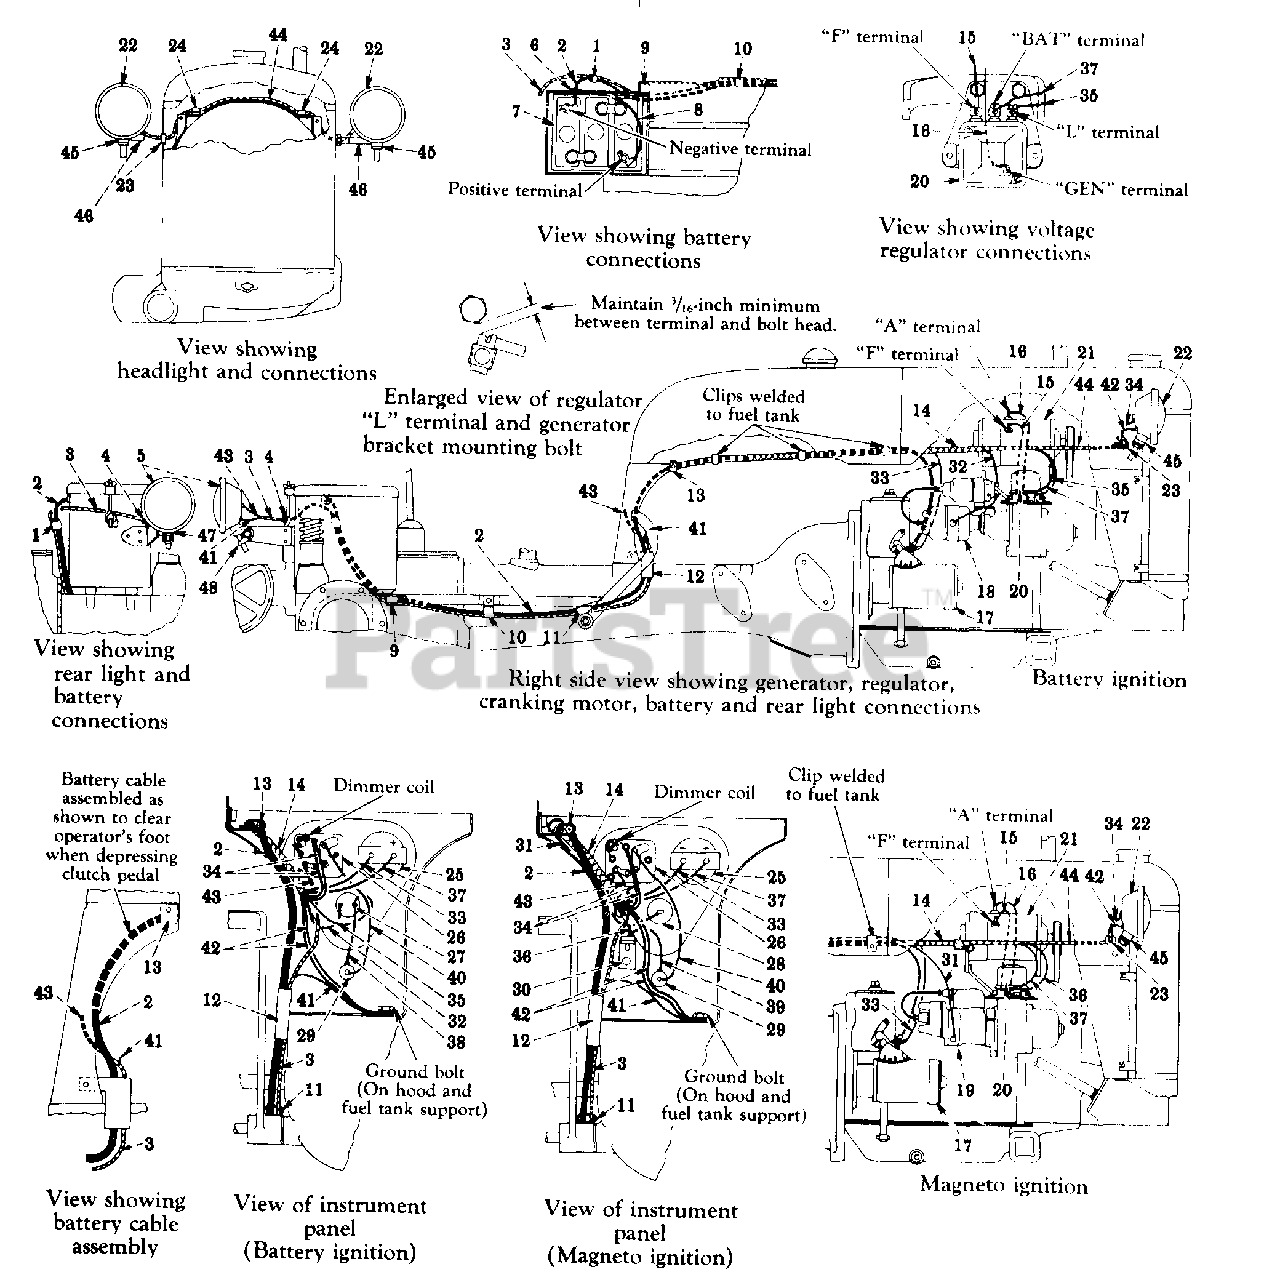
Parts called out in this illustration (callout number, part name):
1	STRAP, WRAPPING CABLE
2	CABLE BATTERY TO CRANKING MOTOR
3	CABLE, LIGHTING SWITCH TO REAR LIGHT
3	HARNESS ASSY, LIGHTING SWITCH TO REAR LIGHT
4	CLIP, REAR LIGHT MOUNTING BRACKET
5	LIGHT ASSY, REAR
6	GROMMET, BATTERY BOX
7	BATTERY - 6 VOLT
8	CABLE, BATTERY TO GROUND
9	CLIP, CABLE
10	CLIP, THIRD BOLT FROM REAR
11	STRAP, WRAPPING CABLE
12	CLIP, INSIDE RIGHT SIDE FUEL TANK SUPPORT
13	CLIP W/NUT, CABLE HARNESS
14	HARNESS ASSY, CABLE
15	CABLE, GENERATOR
16	CABLE GENERATOR
17	MOTOR ASSY CRANKING
18	BATTERY IGNITION
19	MAGNETO ASSY
20	REGULATOR ASSY VOLTAGE
21	GENERATOR ASSY
22	LIGHT ASSY HEAD
23	GROMMET RUBBER NO. 6
24	CLIP W/NUT, HEAD LIGHT CABLE
24	CLIP, CABLE
25	AMMETER ASSY
26	SWITCH ASSY, LIGHTING
27	SWITCH ASSY, BATTERY IGNITION
28	SWITCH ASSY, MAGNETO IGNITION
29	HOUSING, FUSE W/KNOB, IH-356445-R91
30	BLOCK ASSY, MAGNETO IGNITION JUNCTION
31	CABLE, MAGNETO IGNITION SWITCH TO MAGNETO
32	CABLE, BATTERY IGNITION SWITCH TO COIL - ORANGE
33	CABLE AMMETER TO SWITCH
34	CABLE SWITCH TO HEAD LIGHT
35	CABLE, REGULATOR -L- TERMINAL TO SWITCH - LIGHT GREEN
36	CABLE REGULATOR -L- TERMINAL TO JUNCTION BLOCK
37	CABLE, REGULATOR -BAT- TERMINAL TO CHARGE INDICATOR - GRAY
38	CABLE, FUSE HOUSING TO IGNITION SWITCH
39	CABLE FUSE HOUSING TO JUNCTION BLOCK
40	CABLE, FUSE HOUSING TO LIGHTING SWITCH
41	CABLE, REAR LIGHT TO GROUND - PINK
42	CABLE HEAD LIGHT TO GROUND - PINK
43	CABLE, LIGHTING SWITCH TO REAR LIGHT - BLACK
44	HARNESS, HEAD LIGHT CABLE
45	SPACER, HEAD LIGHT
46	POST, HEAD LIGHT
47	SPACER, REAR LIGHT
48	CLAMP, REAR LIGHT
